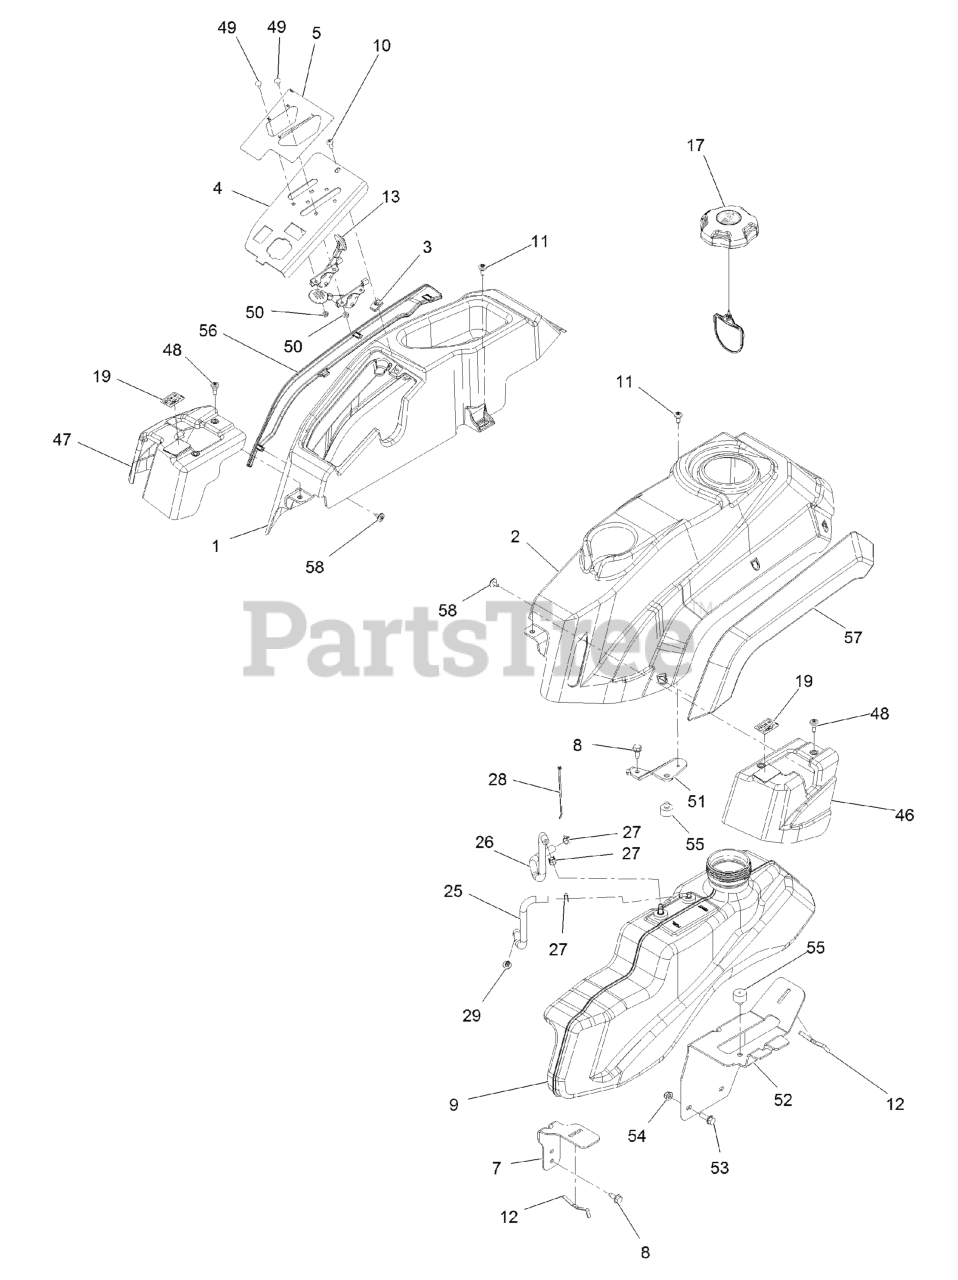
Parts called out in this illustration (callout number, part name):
1	POD-RH, NARROW
2	POD-LH, NARROW
4	PANEL-CONTROL, NARROW
5	DECAL-CONTROL
7	SUPPORT-TANK
8	Screw-HWH 5/16-18 X 3/4 Tf
9	TANK, FUEL
10	SCREW-PRH
11	SCREW-SHOULDER
12	SPRING
13	CABLE-CONTROL, THROTTLE
13	CABLE-CONTROL, CHOKE
17	CAP-FUEL, RATCHETING
19	DECAL-MOTION CONTROL
25	HOSE-FUEL
26	HOSE-FUEL
27	CLAMP-HOSE
28	TIE-CABLE
29	ADAPTOR-ORIFICE
46	Cover, Motion Control LH
47	Cover, Motion Control RH
48	SCREW-SHOULDER
49	BOLT-CARR
50	NUT-LOCK, NI
51	BRACKET-CLAMP
52	BRACKET-SUPPORT TANK
53	SCREW-HHF
54	NUT-HF, NI
55	BUMPER-GROMMET
56	FENDER-RH
57	FENDER-LH
58	SCREW-TORX
